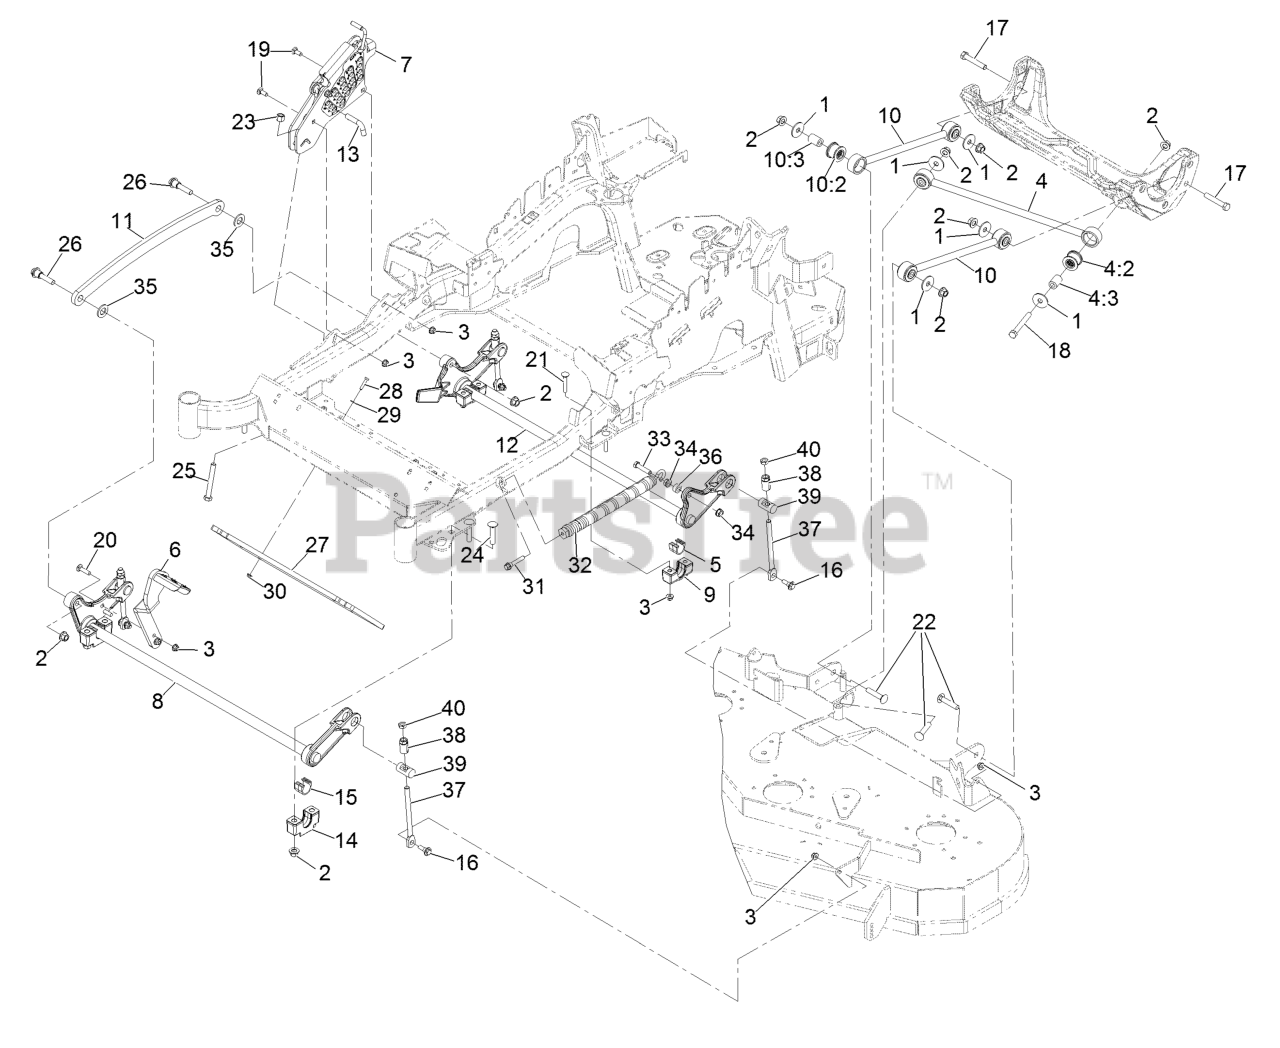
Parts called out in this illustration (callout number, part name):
2	Nut-Lock 1/2-13
3	Nut-Nyloc 3/8-16 Flg
4	Panhard Rod ASM
4:2	Bushing-Suspension, Rubber
5	Bearing-Cross Shaft, Rear
6	Lever-Foot
7	HOC ASM
8	Decklift-Front
9	Support-Cross Shaft, Bearing Rear
10	Deck Strut ASM
10:2	Bushing-Suspension, Rubber
11	Link-Lift, Deck
12	Lift-Deck, Rear
13	Pin-HOC
14	Support-Cross Shaft, Bearing
15	Bearing-Cross Shaft, Front
16	Screw-Hex Flange 3/8-16 X .80
17	Screw-HH 1/2-13 X 3
18	Screw-HH 1/2-13 X 4
19	Bolt-Carriage 3/8-16 X 1
20	Bolt-Carriage 3/8-16 X 1 1/2
21	Bolt-Carriage 3/8-16 X 2 1/4
22	Bolt-Carriage 1/2-13 X 2 1/2
23	Nut-Nyloc 1/2-13
24	Bolt-Carriage 1/2-13 X 2 1/2 Spl Neck
25	Bolt-HH 1/2-13 X 4 Tap
26	Screw-Hex Flange 1/2-13 X 1.90
27	Weight-Toe Board
28	Screw-HH 1/4-20 X 1 1/4
29	Washer-1/4 SAE
30	Nut-Nyloc 1/4-20 Flg
31	Screw-Shcs 3/8-16 X 2.212
32	Spring-Extension
33	Screw-HH 7/16-14 X 2
34	Nut-Whizlock 7/16-14
35	Washer-3/4 SAE
37	Link-Adjuster, Deck Lift
38	Adjuster-Lift, Deck
39	Trunnion
40	Nut-Jam 1/2-13
